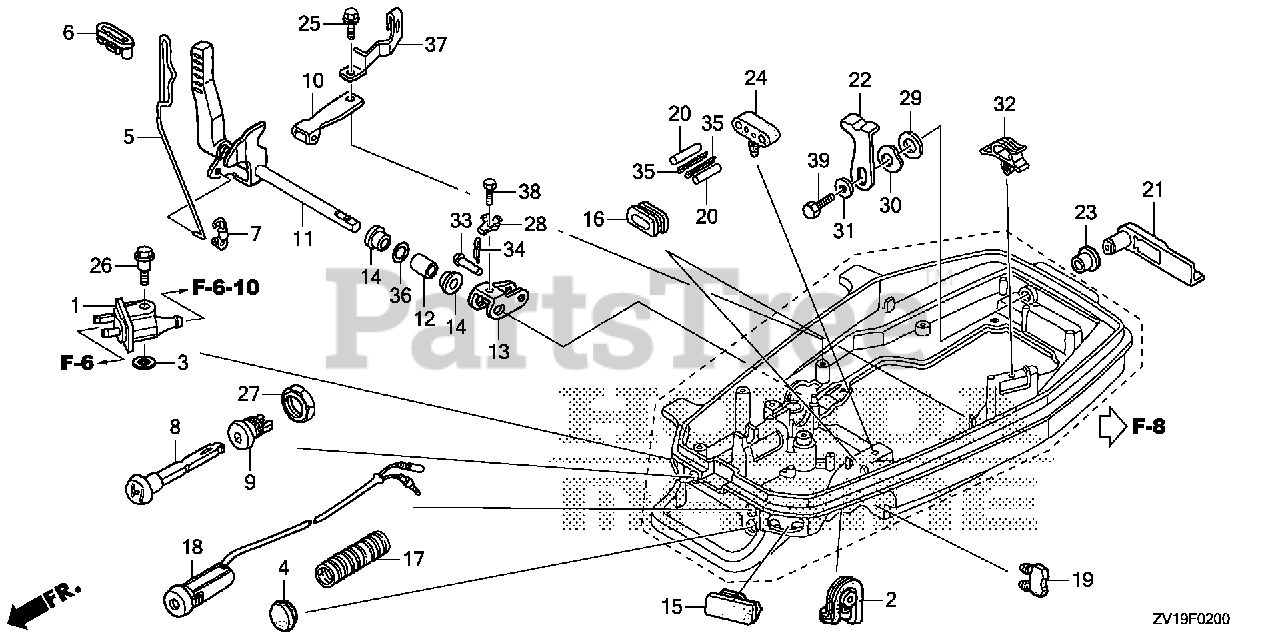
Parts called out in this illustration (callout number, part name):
1	CONNECTOR ASSY., FUEL (B)
2	GROMMET, THROTTLE CABLE
3	WASHER, PIVOT
4	GROMMET B, CASE (LOWER)
6	BUSH, CAM ROD
7	BUSH, LINKAGE
8	KNOB, CHOKE
9	GUIDE, CHOKE KNOB
10	SPRING, CLICK
11	SHAFT, SHIFT
12	COLLAR, SHIFT SHAFT
13	ARM, SHIFT
14	BUSH, SHAFT
15	GROMMET A, CASE (LOWER)
16	GROMMET B, ALTERNATOR WIRE
17	TUBE, WIRE CLAMP
18	LAMP ASSY., INDICATOR
19	RUBBER C, MOUNTING
20	PIN, SHEAR
21	LEVER, COVER LOCK *NHB14M* (AQUA MARINE SILVER METALLIC)
22	HOOK, COVER LOCK
23	BUSH, COVER LOCK
24	HOLDER, PARTS
25	BOLT, FLANGE (6X12) (CT200)
26	BOLT, SPECIAL (6X22) (CT200)
27	NUT, HEX. (16MM) DUAL QTY = (2) (SINGLE)
28	WASHER, TONGUED
29	WASHER (14MM)
30	WASHER, WAVE (14MM)
31	WASHER (6MM)
32	CLIP, CABLE
33	PIN (5X34)
34	PIN, COTTER (1.6MM)
35	PIN, COTTER
36	O-RING (9.8X2.4)
37	CLIP, TUBE
38	BOLT, HEX. (5X16)
39	BOLT, HEX. (6X16)
